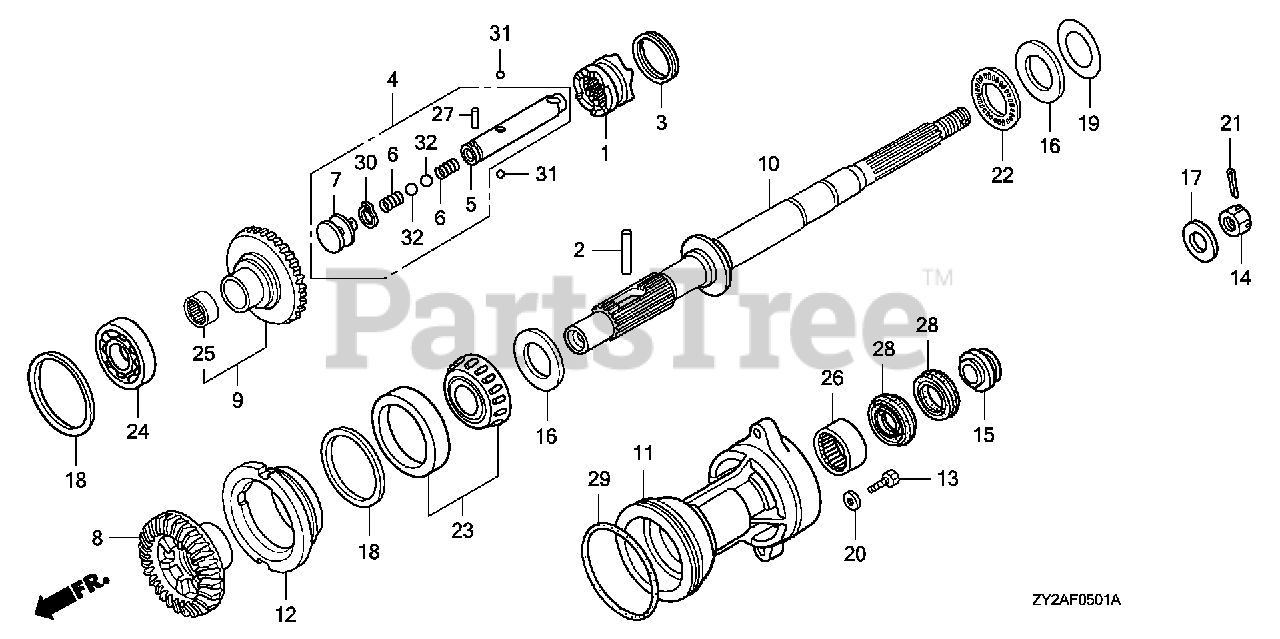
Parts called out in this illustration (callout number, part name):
1	SHIFTER, CLUTCH
2	PIN, SHIFTER (8X50)
3	RING, CROSS PIN
4	SLIDER, SHIFT
5	SLIDER, SHIFT
6	SPRING, SHIFT
7	PLATE, SHIFT
8	GEAR, BEVEL (FORWARD 28T) (COUNTER ROTATION)
9	GEAR, BEVEL (RVS. 28T) (COUNTER ROTATION)
10	SHAFT, PROPELLER (COUNTER ROTATION)
11	HOLDER, PROPELLER SHAFT *NH282MU* (OYSTER SILVER METALLIC-U)
12	HOLDER, BEARING (COUNTER ROTATION)
13	BOLT, HEX. (12X45)
14	NUT, CASTLE (18MM)
15	WASHER, PROPELLER THRUST
16	WASHER, THRUST BEARING
17	WASHER, PROPELLER
18	SHIM A, BEVEL (0.10)
18	SHIM B, BEVEL (0.15)
18	SHIM C, BEVEL (0.30)
18	SHIM D, BEVEL (0.50)
19	SHIM A, THRUST (0.10)
19	SHIM B, THRUST (0.15)
19	SHIM C, THRUST (0.30)
19	SHIM D, THRUST (0.50)
20	WASHER, PLAIN (12MM)
21	PIN, SPLIT (4.0)
22	BEARING, THRUST (F)
23	BEARING, TAPER (50X90X21.5)
24	BEARING, ANGULAR (50X90X30.2)
25	BEARING, NEEDLE (28X39X30)
26	BEARING, NEEDLE (32X42X30)
27	ROLLER (4X13.8)
27	ROLLER (3X13.8)
28	SEAL, WATER (30X45X7)
29	O-RING (105X3.1)
30	CIRCLIP (OUTER) (15MM)
31	BALL, STEEL (#7) (7/32)
32	BALL, STEEL (#12) (3/8)
